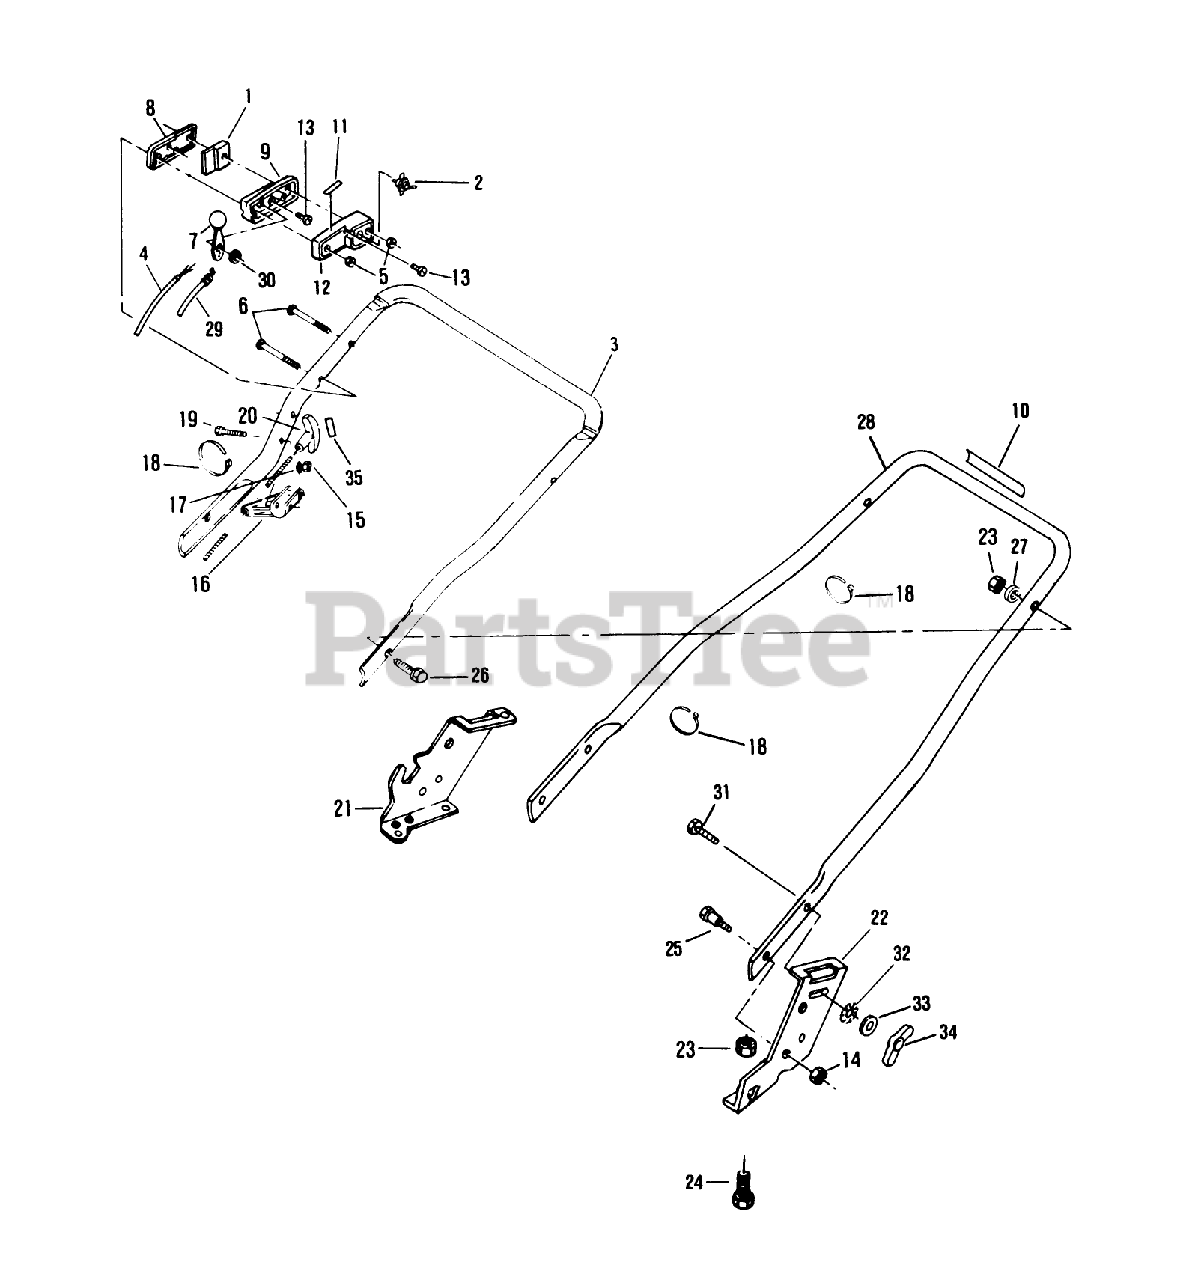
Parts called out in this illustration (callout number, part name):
5	NUT C/LOCK E
6	SCREW
7	LEVER&KNOB AY WES
8	OUTER CONTROL CASE
13	SCREW
14	NUT-JAM, LOCKING
15	LOCKNUT E
17	WASHER
23	NUT-LOCK F
25	BOLT
27	WASHER-CURVED
29	CABLE THROT WES
30	WASHER-SPRING
32	LOCK WASHER LARSON
33	WASHER
34	NUT-WING
35	CLIP-STARTER
